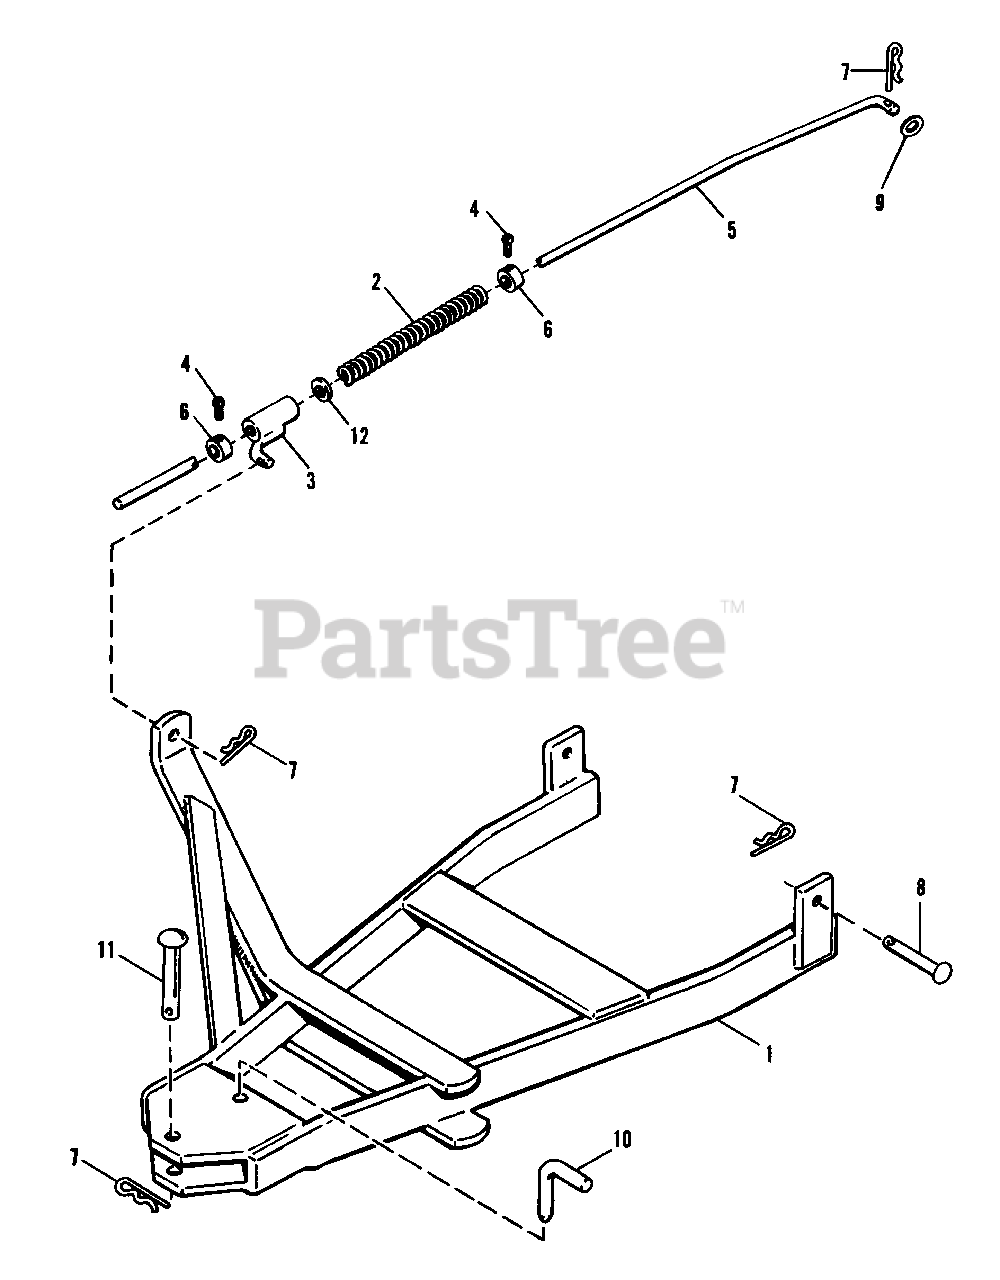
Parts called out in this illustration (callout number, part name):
1	BAR ASSY, Push
3	GUIDE ASSY, Rod
4	SETSCREW, Sq. Hd, 5/16-18 x 1/2
6	COLLAR
7	CLIP, Spring
8	PlN
9	WASHER, Plain, 1/2 x 1-1/4
